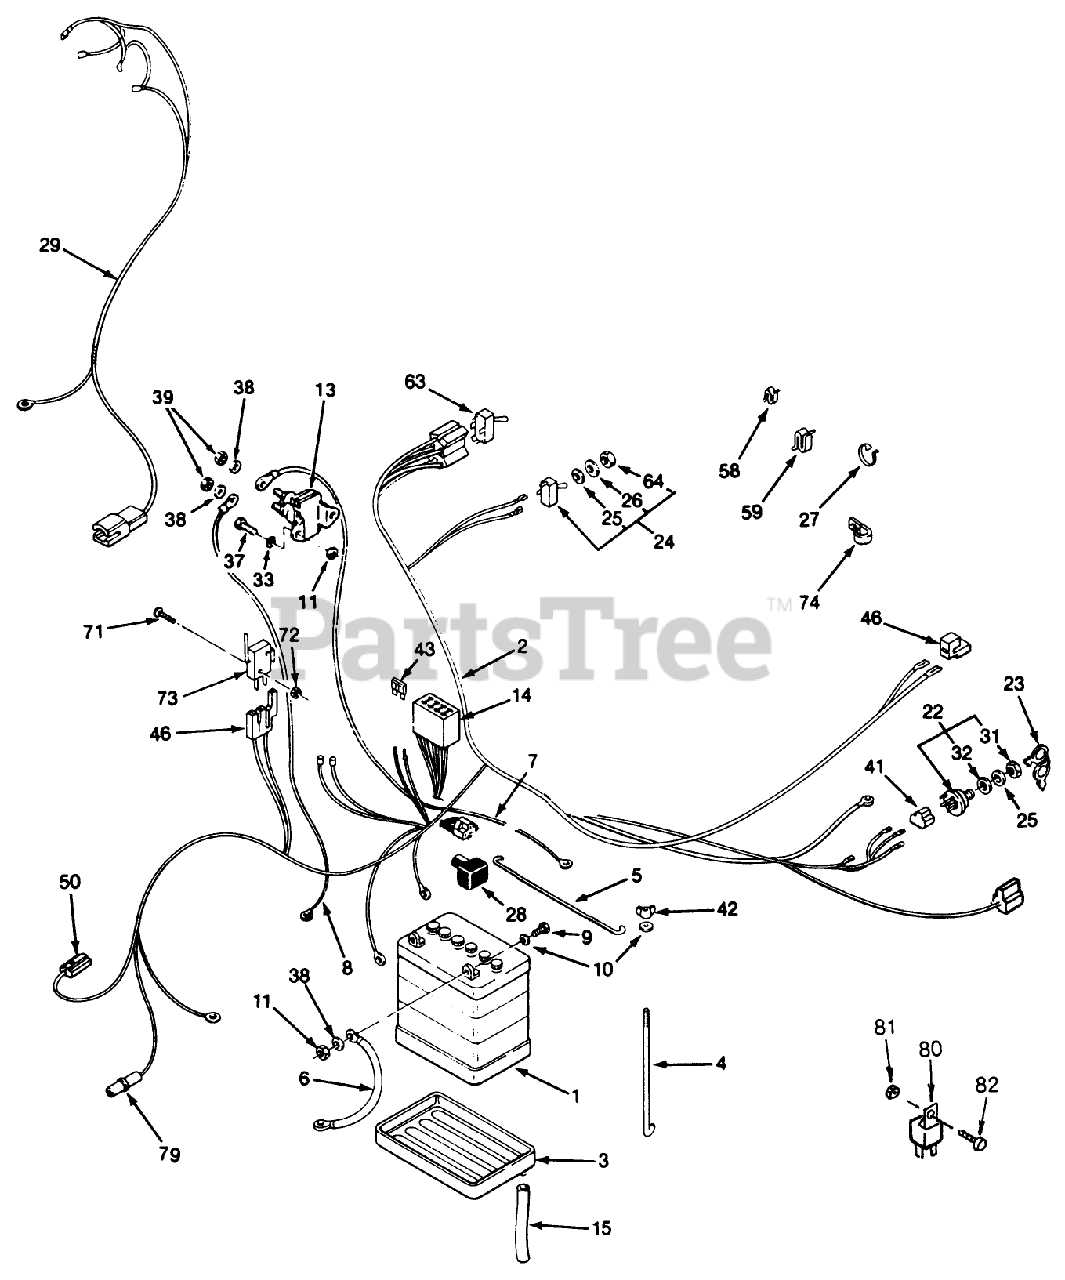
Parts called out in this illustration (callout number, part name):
3	TRAY-BATTERY
5	ROD-BATTERY HOLD DWN
6	WIRE -BLACK
7	WIRE - 14" BLACK
9	SCREW-HH
10	WASHER-FLAT
11	NUT-HEX
15	TUBE-BATTERY DRAIN
24	SWITCH-LIGHTS
26	Washer
33	WASHER-LOCK/EXT
38	WASHER-LOCK
39	NUT-JAM
42	NUT-WING
43	FUSE-BLADE, 15 AMP
46	CONNECTOR BODY
50	CONNECTOR BODY ELECT
58	CLIP
63	PTO-SWITCH W/COVER
73	SWITCH - CLUTCH
74	CLAMP
80	RELAY
